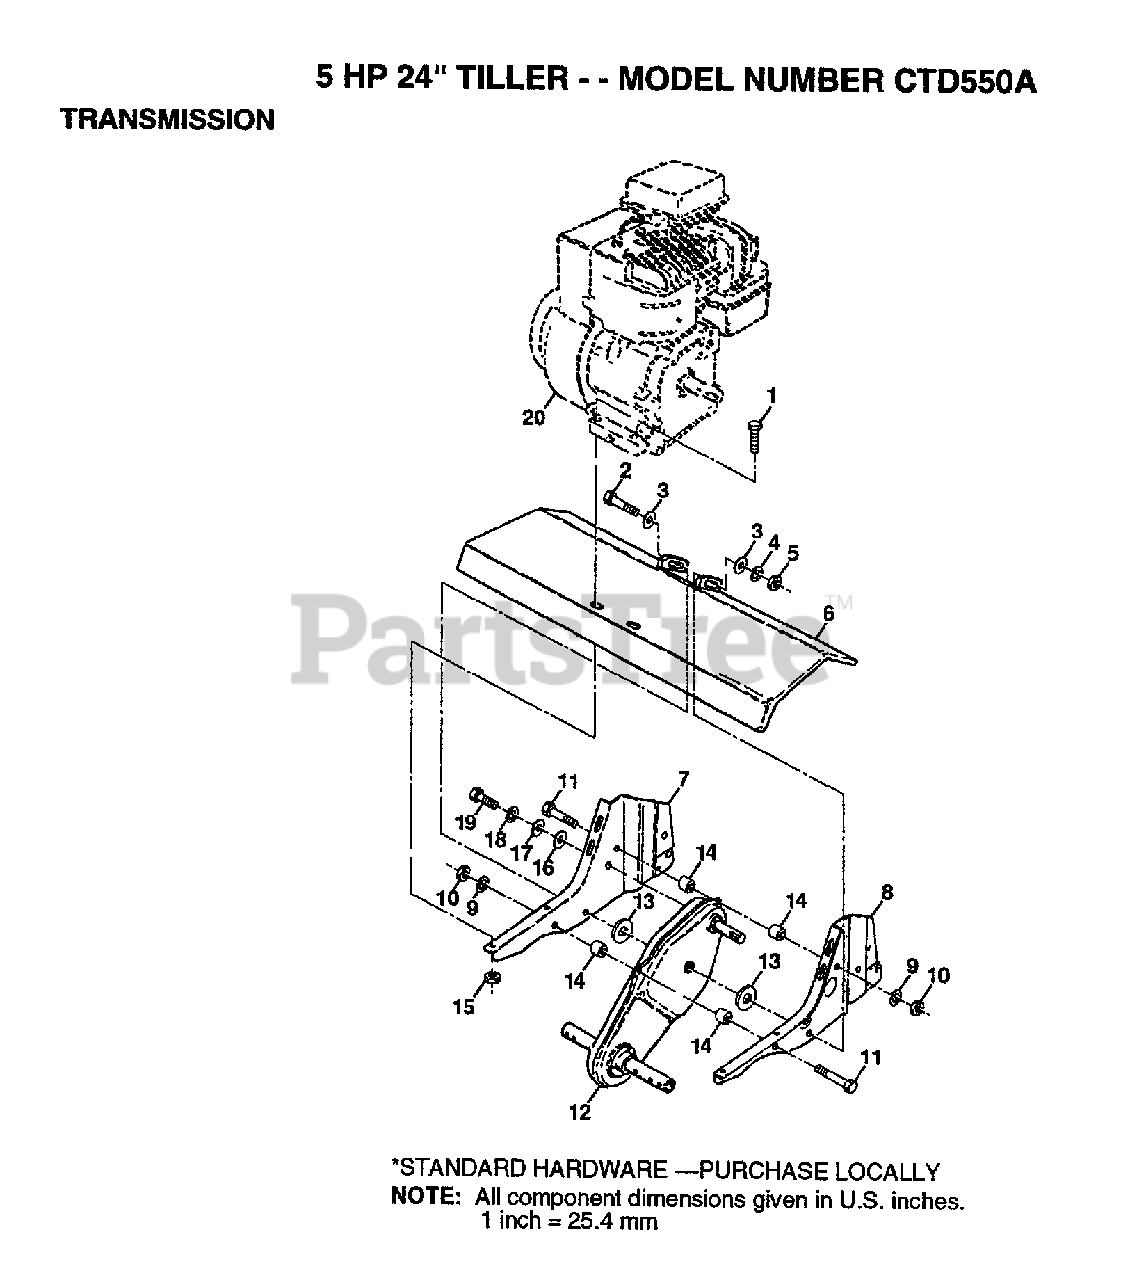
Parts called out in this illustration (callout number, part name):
1	BOLT.HEX.5/16-1.5
2	BOLT.3/8-24X3.75
3	WASHER
4	LOCKWASHER
5	GRIPCO NUT
8	BRACKET.ENG.LH.
9	LOCKWASHER
10	NUT.HEX.5/16-18
14	SPLIT SPACER RT
16	WASHER
17	WASHER
18	LOCKWASHER
19	BOLT
